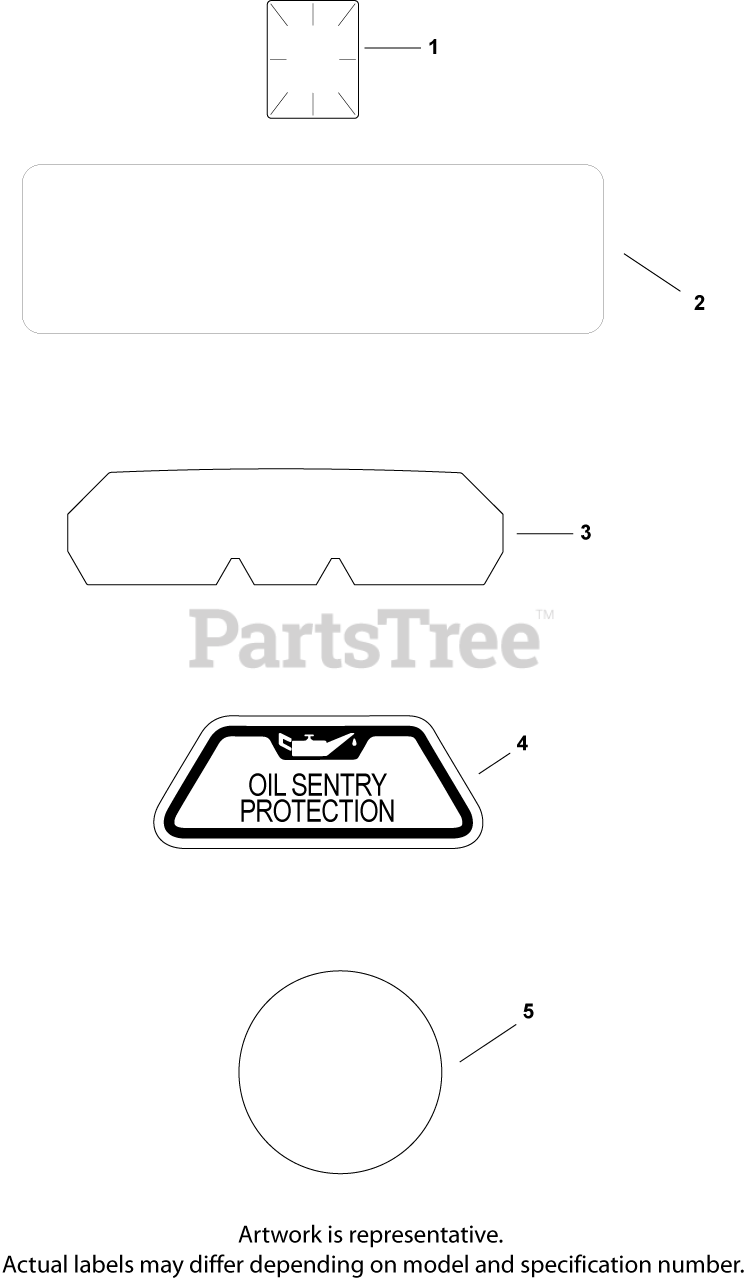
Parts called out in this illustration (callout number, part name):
1	DECAL, CLEAR LAMINATE USE 25 113 70-S
2	DECAL, 23 HP - DISCONTINUED
3	DECAL, HEAT REFLECTIVE
4	DECAL, OIL SENTRY - (#DSC)
5	DECAL, GRASS SCREEN
